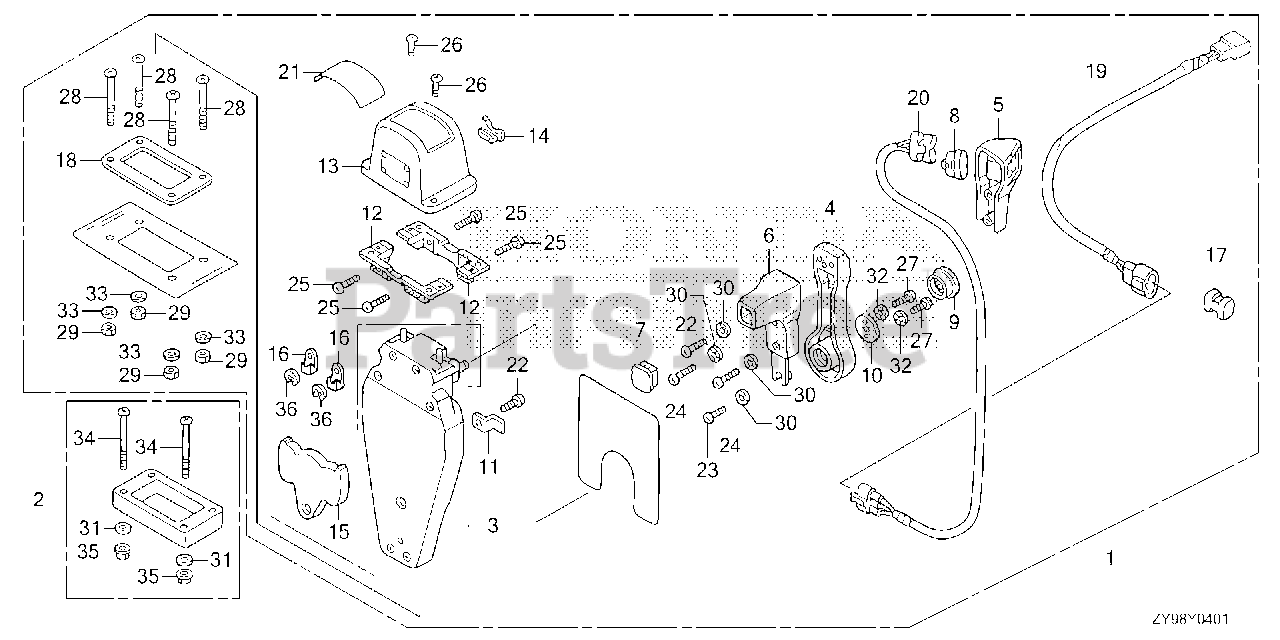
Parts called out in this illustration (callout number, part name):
1	BOX KIT, REMOTE CONTROL (TOP MOUNT SINGLE)(L)
2	SPACER KIT, REMOTE CONTROL BOX (TOP MOUNT SINGLE)
3	HOUSING ASSY., R. (INNER) (TOP MOUNT)
4	HANDLE, REMOTE CONTROL
5	COVER, R. GRIP
6	GRIP, REMOTE CONTROL HANDLE
7	CAP, GRIP
8	CAP, SWITCH
9	BUTTON, THROTTLE
10	PLATE, HANDLE
11	PLATE, CABLE CLAMP
12	BRACKET, REMOTE CONTROL HOUSING
13	HOUSING, REMOTE CONTROL BOX
14	HOUSING, LEAD
15	PLATE, DWELL
16	TERMINAL, CABLE
17	SPACER, CABLE CLAMP
18	GASKET, SINGLE
19	SUB-HARNESS ASSY., POWER TRIM-TILT (B)
20	SWITCH ASSY., POWER TRIM-TILT (B)
21	MARK, REMOTE CONTROL (SINGLE)
22	SCREW, PAN (5X16)
23	SCREW, PAN (5X10)
24	SCREW, PAN (5X20)
25	SCREW, PAN (5X18)
26	SCREW, PAN (4X10)
27	SCREW, PAN (6X18)
28	SCREW, PAN (5X40)
29	NUT, HEX. (5MM)
30	WASHER, LOCK (5MM)
31	WASHER, PLAIN (5MM)
32	WASHER, LOCK (6MM)
33	WASHER, PLAIN (5MM)
34	SCREW, PAN (5X65)
35	NUT, HEX. (5MM)
36	E-RING (6MM)
